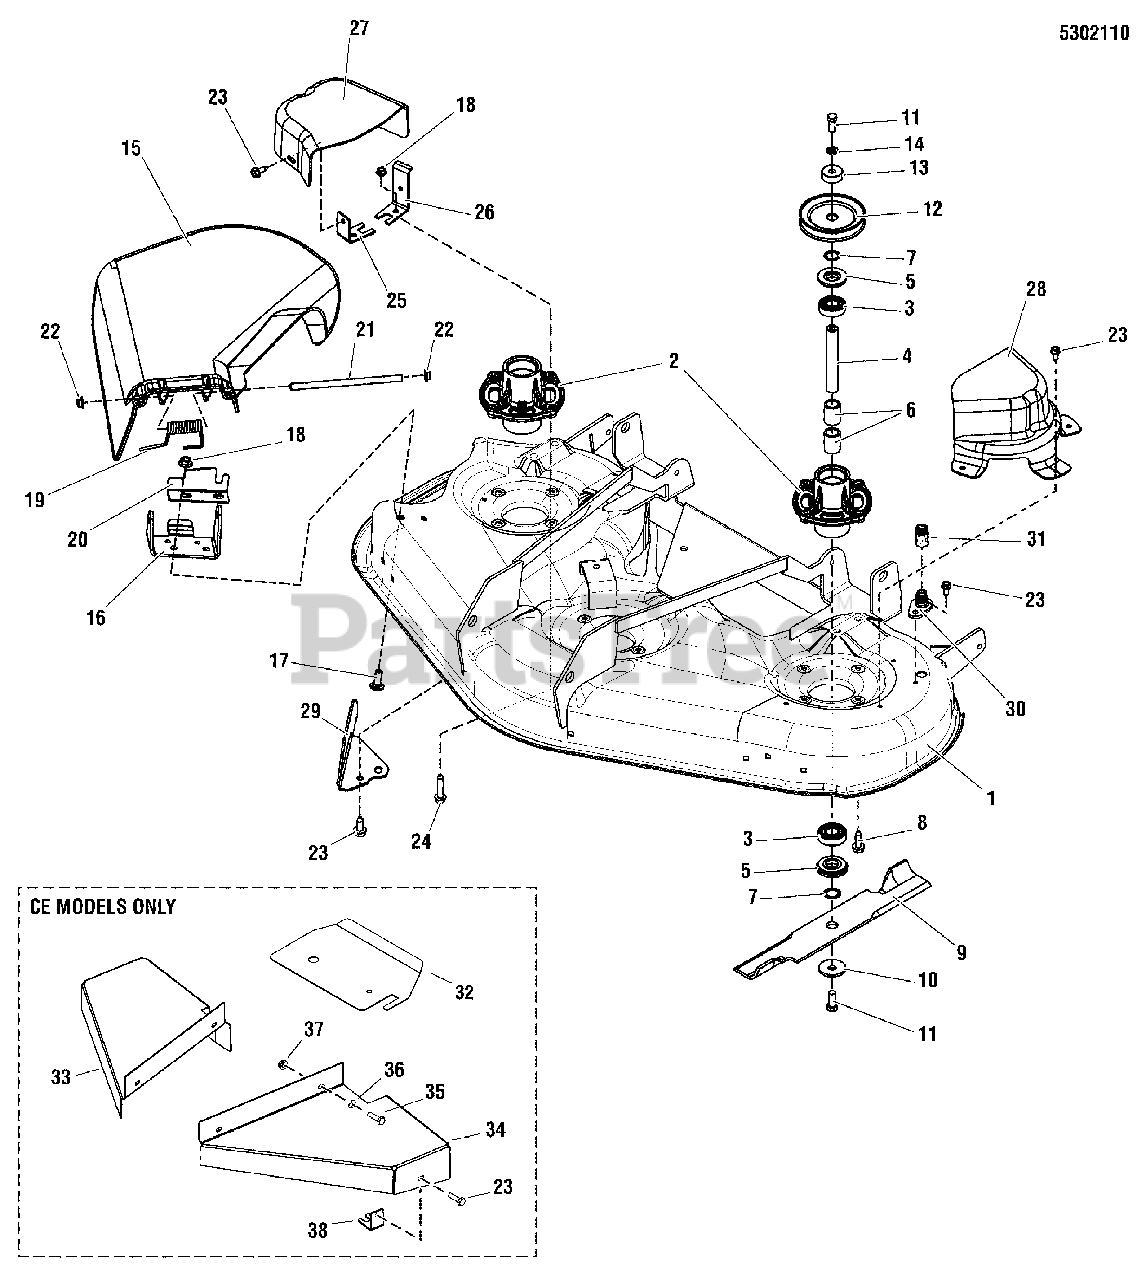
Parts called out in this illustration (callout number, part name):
1	DECK SHELL, W/ DECALS, 52
2	HOUSING, SPINDLE, CAST STEEL, MACHINED
3	BEARING, BALL, 20MM 46" MWR
4	SHAFT, SPINDLE, 20MM DIA 134.60MM LG
5	SHIELD-ARBOR, 2.050OD 46" MWR
6	SPACER, BEARING, PWDR MTL 46" MWR
7	RING, SELF LOCKING 46" MWR
8	SCREW, HEX WSHR HD TAPTT5/16-18X1.000BLK
9	BLADE, MOWER 18.50LG 52" MWR
10	WASHER, SPRING 0.475IDX1.75ODX.156TH BLK
11	CAPSCREW, HEX HD 7/16-14X1.000 G5 BLK
12	PULLEY, 5.5 OD 11GA SPLIT 52" MWR
13	SPACER, LOWER DRIVE 46" MWR
14	LOCKWSHER, SPRING .438 BLK
15	DEFLECTOR-DISCH PLASTIC 46/52 DECKS
16	HINGE, DEFLECTOR, 52"
17	BOLT, RD HD SH SQ NK 5/16-18X0.750 G5 BLK
18	NUT, 5/16-18 HEX SERRATED FLANGE (SMALL)
19	SPRING, TORS DEFLECTOR 2.16LG 46" MWR
20	PLATE, DEFLECTOR CLOSEOFF
21	ROD, DEFLECTOR, YELLOW ZINC
22	NUT, PUSH, 5/16 BZ
23	SCREW, HEX WSHR HD TAPTT5/16-18X0.750BLK
24	SCREW, HEX WSHR HD TAPTT5/16-18X1.500 BLK
25	BRKT, BELT COVER, SHORT
26	BRKT, BELT COVER, LONG W/ TAB
27	COVER, BELT BLACK POLY RH 46 + 52" MWRS
28	COVER, BELT LH BLACK POLY 52" MOWER
29	BAFFLE, PINCHOFF
30	ADAPTER, WASHOUT PORT 46+52" PLASTIC
31	WASHOUT PORT-CONNECTOR, 46+52" BLK POLY
32	PLATE, BELT GUARD
33	PLATE, DECK GUARD - RH
34	PLATE, DECK GUARD - LH
35	BOLT, 5/16-18 X 1 GD5 YZ
36	WASHER, 5/16 SAE
37	NUT, 5/16-18 HEX NYLOCK FLANGE
38	BRKT, BELT COVER, FRONT
